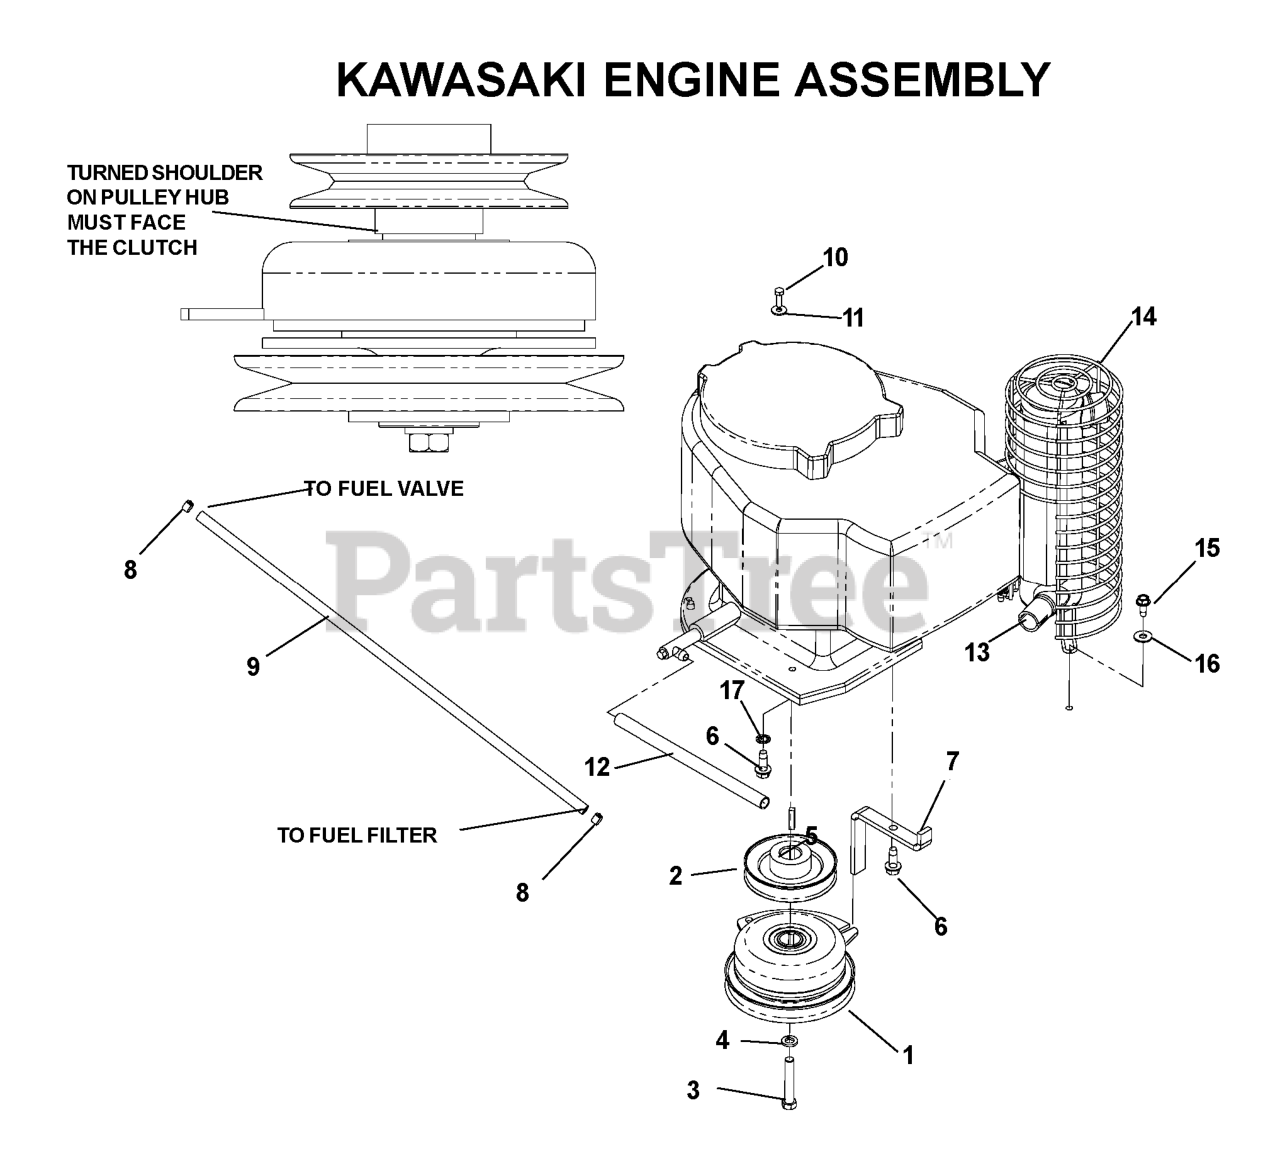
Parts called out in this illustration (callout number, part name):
3	BOLT 7/16F X 2 1/2
4	WASHER 7/16 LOCK
5	KEY 1/4 SQ X 1 1/8
6	BOLT 3/8-16 X 1.0
7	CLUTCH TIE DOWN
8	HOSE CLAMP
9	FUEL LINE 24"
10	HEX HEAD SCREW M6 X 1 X 20
11	WASHER 1/4 FLAT
12	OIL DRAIN HOSE
13	MUFFLER KAW
14	MUFFLER GUARD
15	BOLT 5/16-18 X 3/4
16	WASHER 5/16 FLAT
17	WASHER
539104415	KAW PIGTAIL
539105637	CLUTCH HARNESS
539108120	JAM NUT 1/4C (2 2 PW01)
